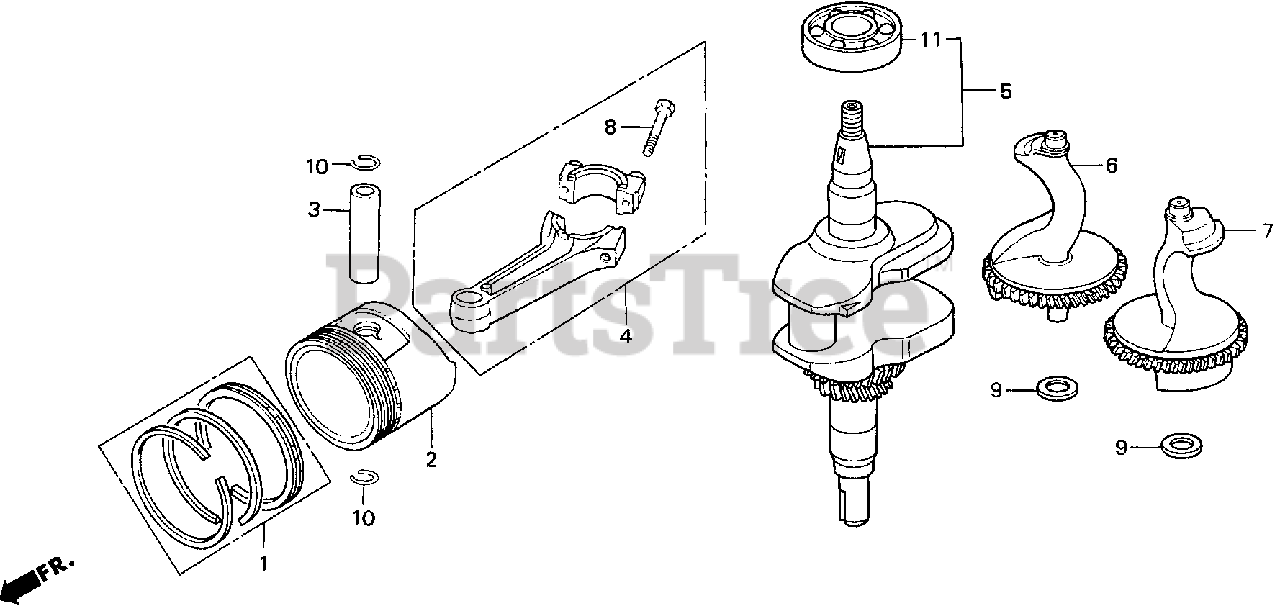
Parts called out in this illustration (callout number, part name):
1	RING SET, PISTON (STD) (NIPPON)
1	RING SET, PISTON (0.25) (NIPPON)
1	RING SET, PISTON (0.50) (NIPPON)
1	RING SET, PISTON (0.75) (NIPPON)
2	PISTON (STD)
2	PISTON (0.25)
2	PISTON (0.50)
2	PISTON (0.50) (NOT AVAILABLE)
2	PISTON (0.75)
2	PISTON (0.75) (NOT AVAILABLE)
3	PIN, PISTON
4	ROD ASSY., CONNECTING
4	ROD ASSY., CONNECTING (0.25 LOWER SIZE)
4	ROD ASSY., CONNECTING (STD)
5	CRANKSHAFT
5	CRANKSHAFT (NOT AVAILABLE)
6	WEIGHT A, BALANCER (NOT AVAILABLE)
6	WEIGHT A, BALANCER
7	WEIGHT B, BALANCER (NOT AVAILABLE)
7	WEIGHT B, BALANCER
8	BOLT, CONNECTING ROD
9	WASHER, THRUST (15MM)
10	CLIP, PISTON PIN (20MM)
11	BEARING, RADIAL BALL (6207)
